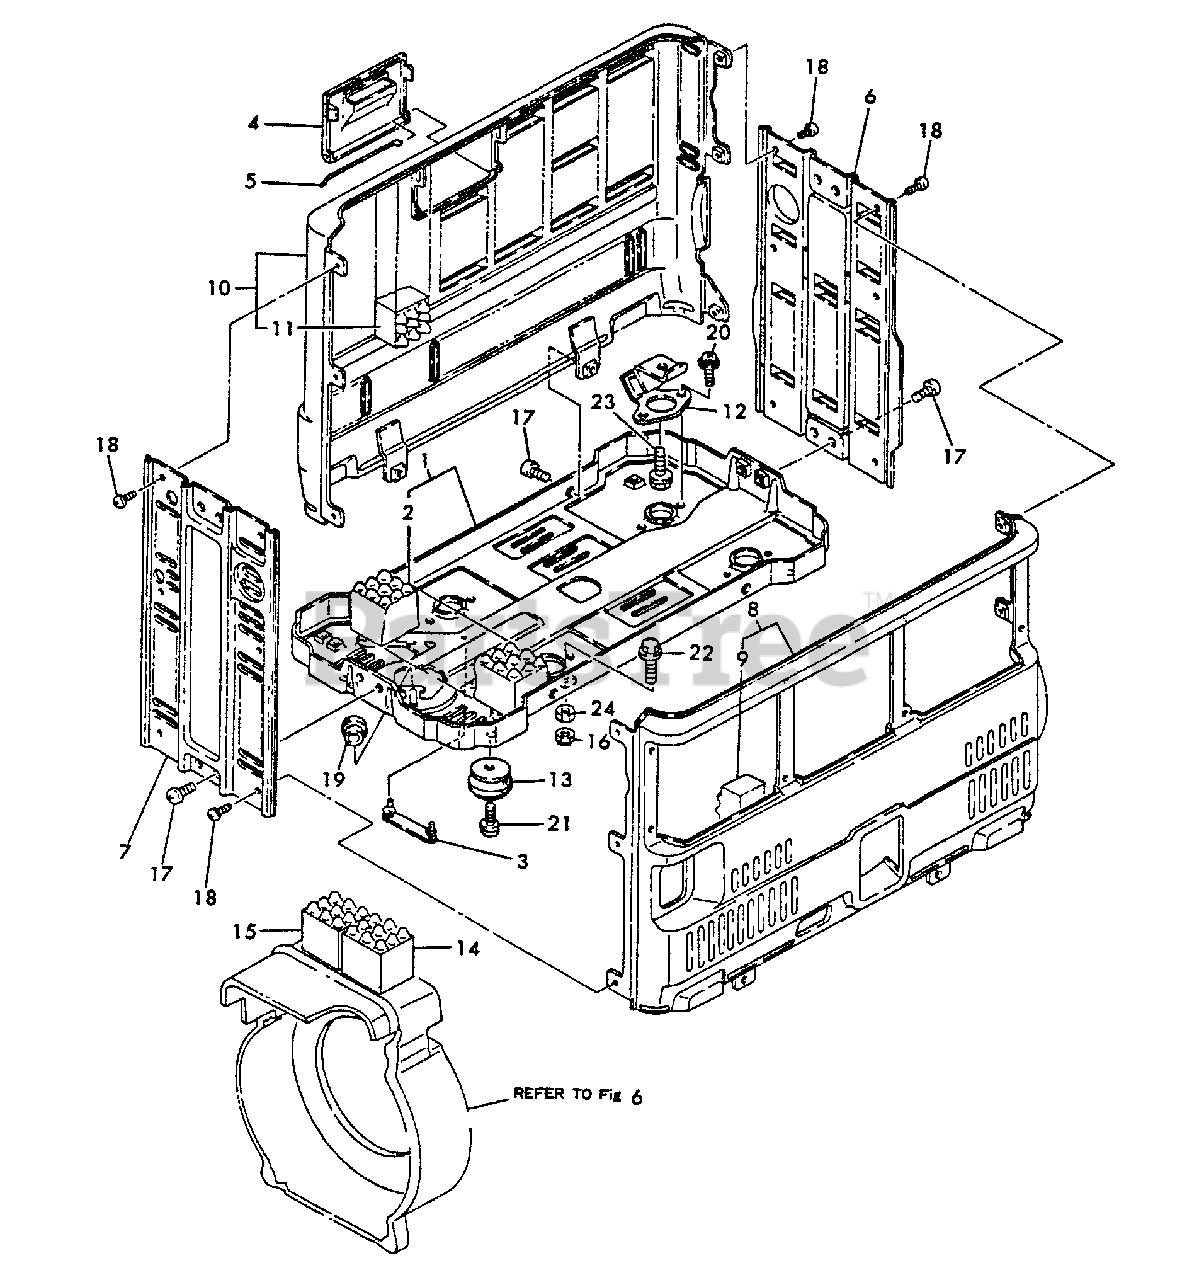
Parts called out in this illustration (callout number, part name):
1	CASE BOTTOM
2	URETHANE FOAM (E)
3	HOLDER, TOOL
4	PLUG, BLIND
5	SPRING, HINGE
6	CASE, SIDE - RIGHT
7	CASE, SIDE - LEFT
8	CASE, FRONT
9	URETHANE FOAM (C)
10	CASE ASSY, REAR
11	URETHANE FOAM (D)
12	DAMPER (A)
13	DAMPER (B)
14	URETHANE FOAM (A)
15	URETHANE FOAM (B)
16	NUT, EARTH
17	SCREW M6×10
18	SCREW M4×8
19	GROMMET
20	SCREW - 6×12
21	SCREW - 6×12
22	BOLT - 6×16 -- PLATED
23	BOLT - 8×14 -- PLATED
24	LOCKNUT - 6 -- PLATED
